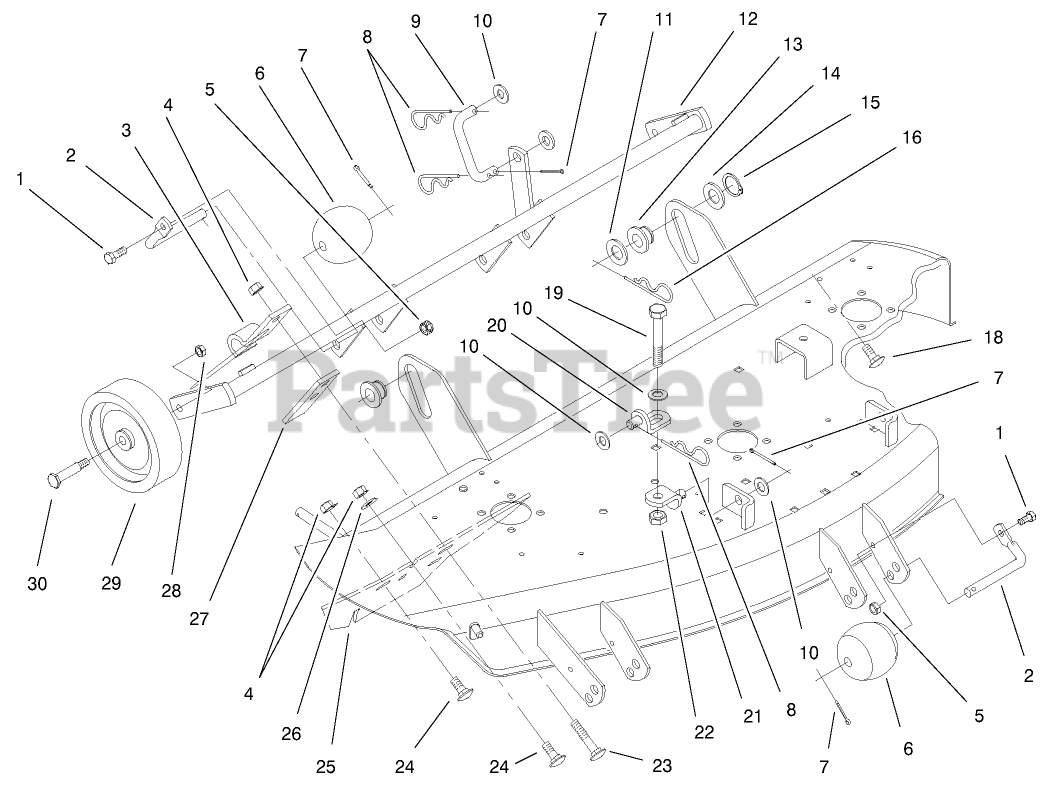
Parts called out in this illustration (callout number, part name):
1	SCREW-HH
2	SHAFT-ROLLER
3	BRACKET-PIVOT
4	NUT-LOCK, NI
5	NUT-LOCK, NI
6	ROLLER
7	PIN-COTTER
8	PIN-COTTER, HAIR
9	LINK-REAR
10	WASHER-FLAT
11	WASHER-FLAT
12	SUPPORT-GAGE WHEEL ASM
13	ROLLER-LIFT
14	WASHER-FLAT
15	RING-RETAINING
16	PIN-HAIR
18	SCREW-CARR
19	SCREW-HH
20	BRACKET-LIFT, LOWER
21	BRACKET-LIFT, UPPER
22	NUT-JAM
23	SCREW-CARR
24	SCREW-CARR
25	PLATE-WEAR RH
26	WASHER-FLAT
29	WHEEL
30	BOLT-SHOULDER
